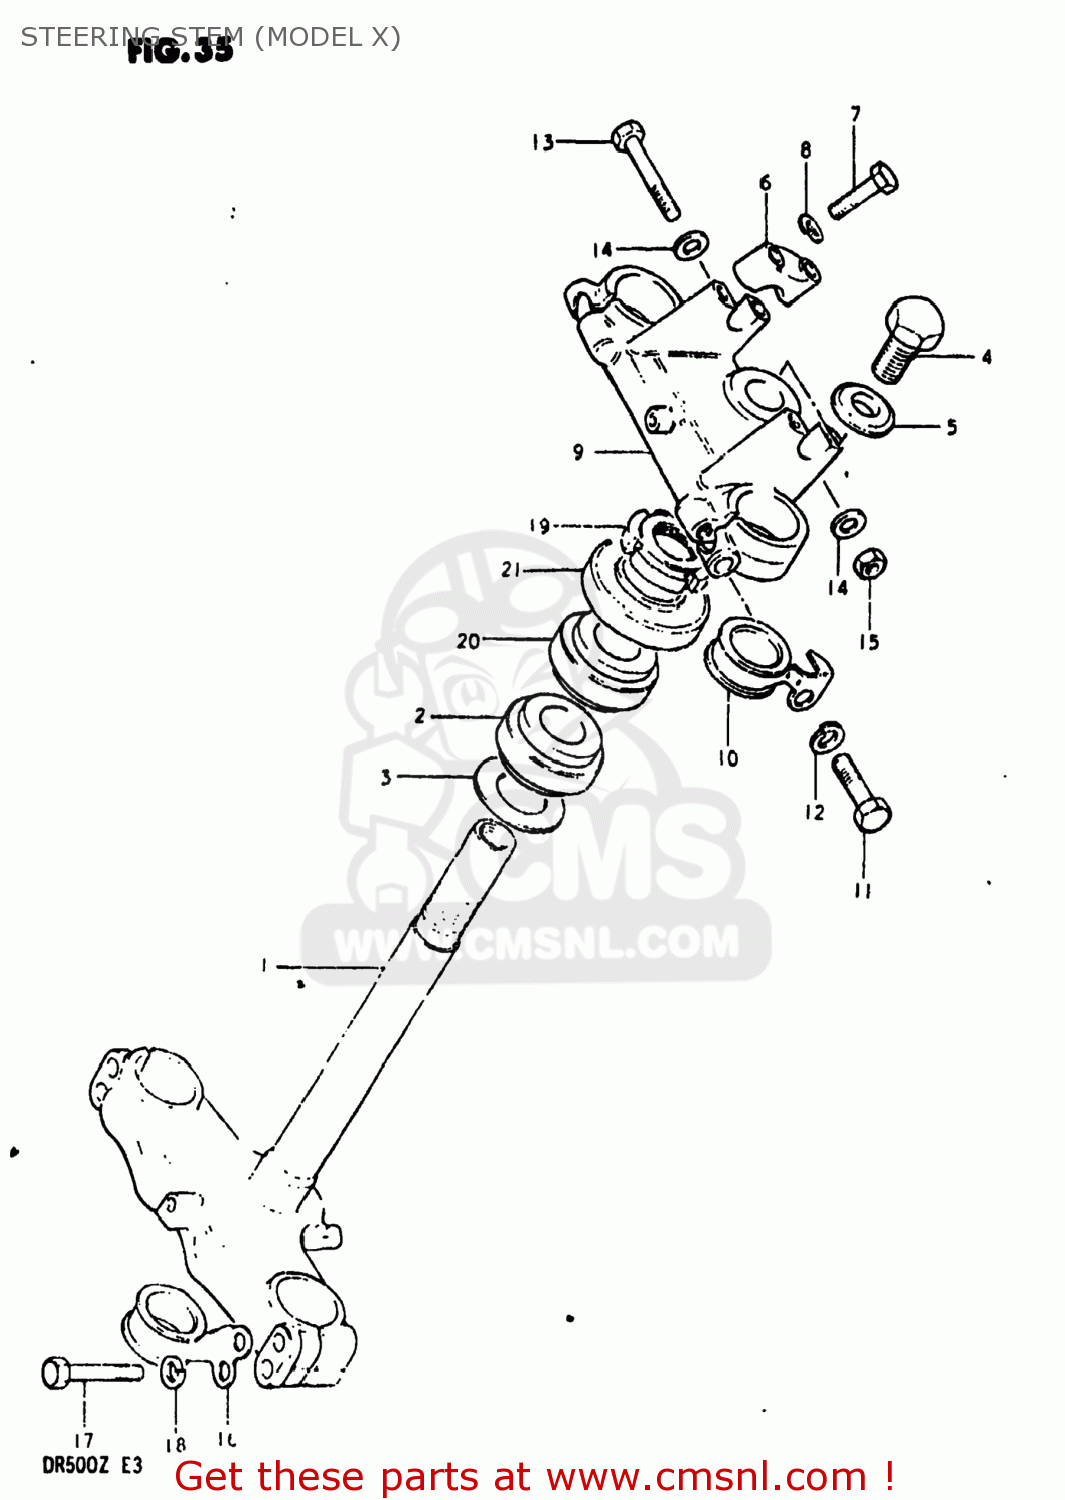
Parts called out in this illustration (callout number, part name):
1	STEM,STEERING
2	BEARING
3	WASHER,THRUST
4	BOLT
5	WASHER
6	HOLDER,HANDLEBAR
7	BOLT
8	LOCK WASHER
9	HEAD,STEERING STEM
10	GUIDE,CABLE
11	BOLT
12	LOCK WASHER
13	BOLT 8X50
14	WASHER
15	NUT
16	GUIDE,CABLE
17	BOLT 8X45
18	LOCK WASHER
19	NUT,STEERING STEM(25X44X10)
20	TAPER,ROLLER BEARING
21	DUST SEAL,STEERING UPR
